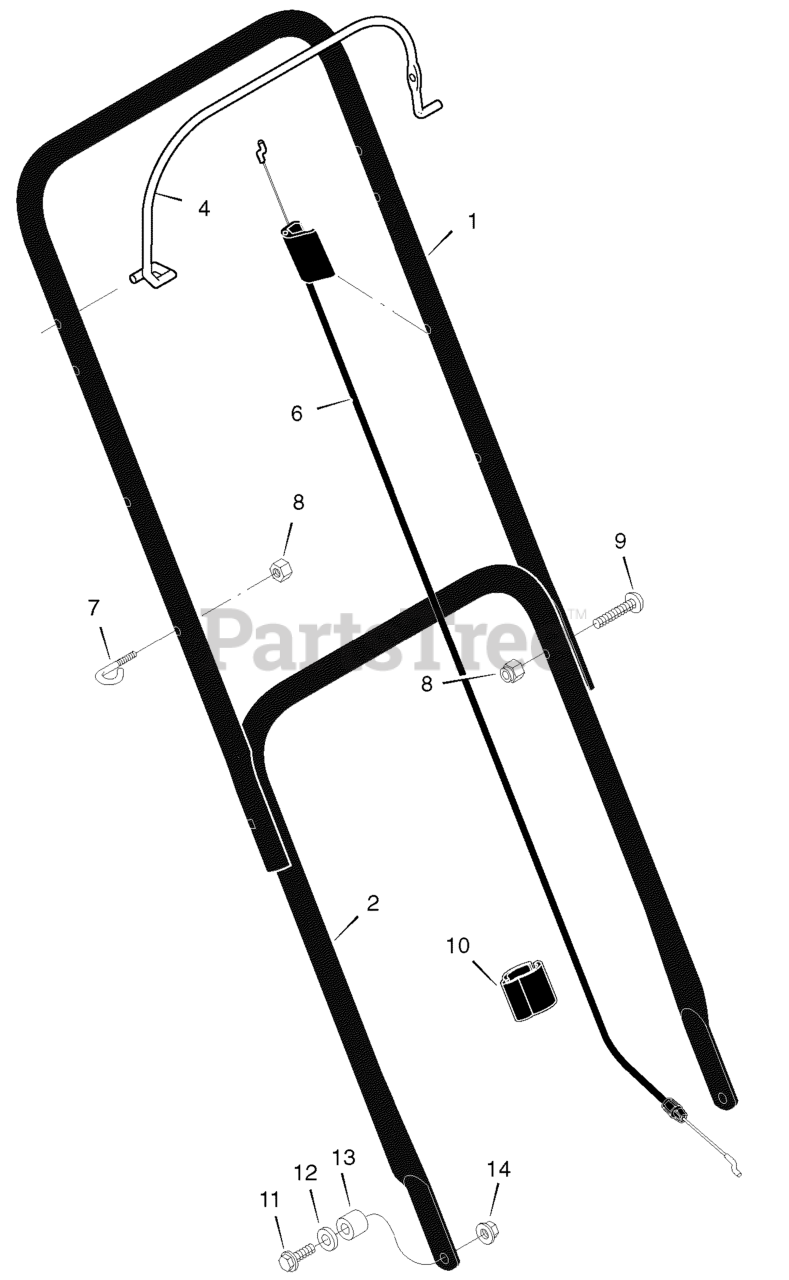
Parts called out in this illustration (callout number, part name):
1	Handle, Upper (Black)
2	Handle, Lower (Black)
4	Lever, Stop
6	Engine Stop Cable
7	Guide, Rope
8	Locknut
10	Clip, Cable
11	Bolt
12	Washer
13	Spacer
14	Nut
